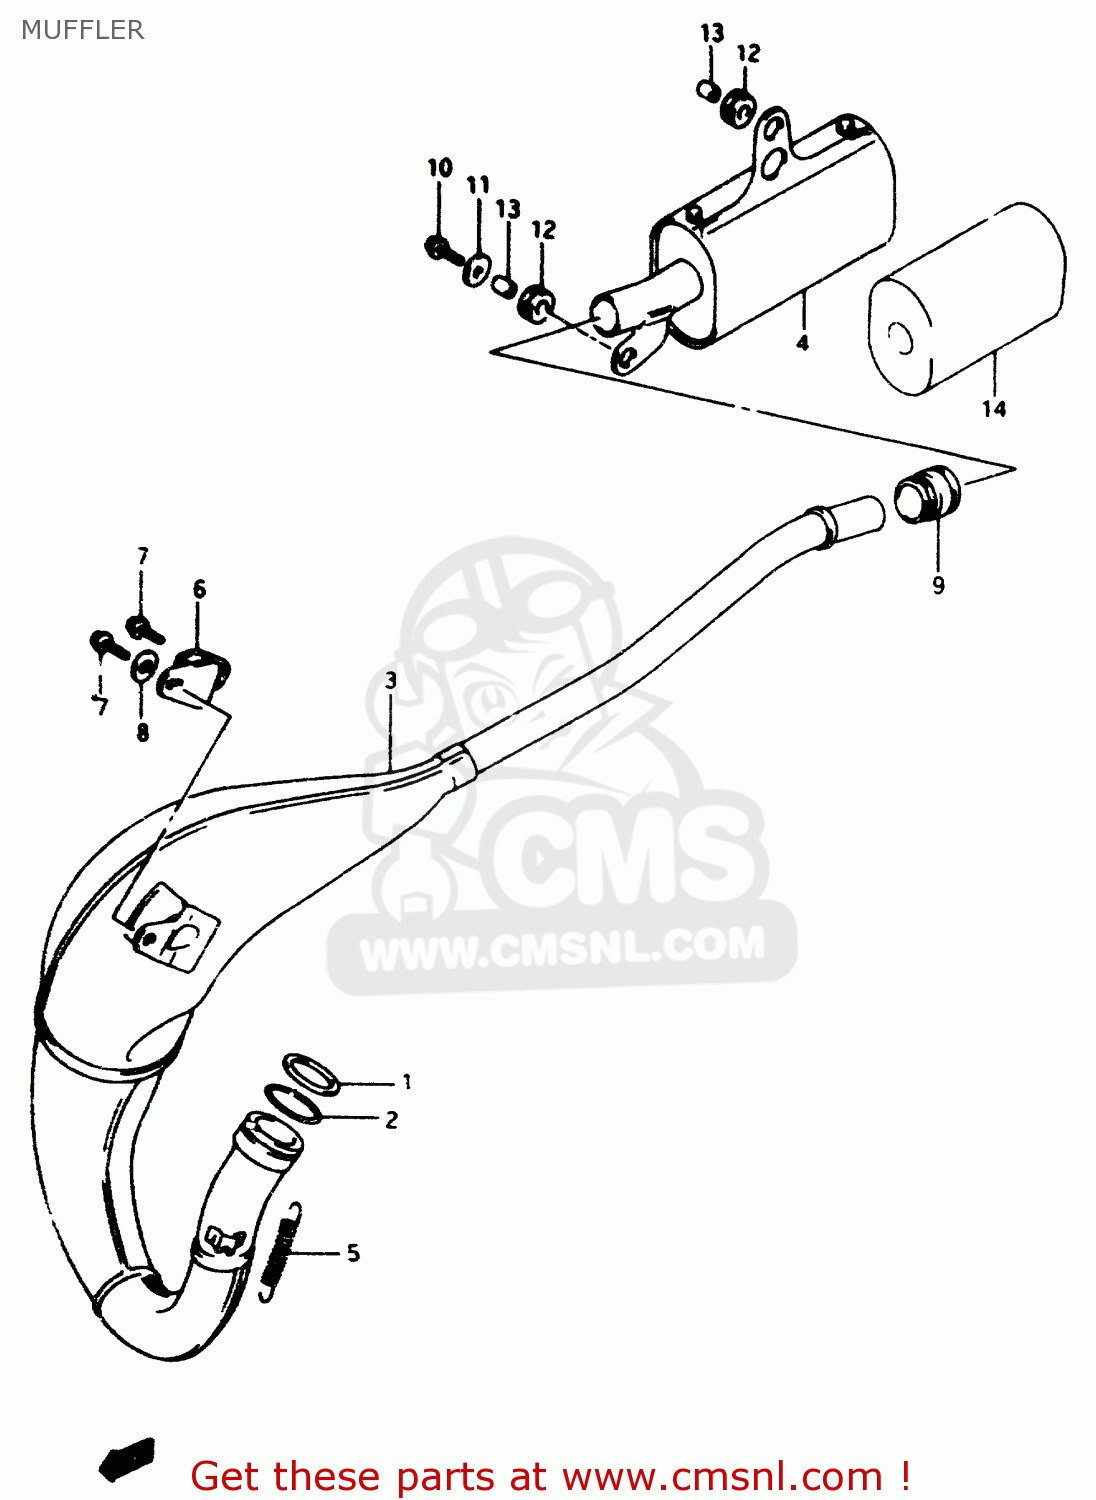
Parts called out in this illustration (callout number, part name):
1	WASHER,EXH FLANGE
2	O RING,EXH FLANGE
3	BODY,MUFFLER 1ST
4	BODY,MUFFLER,SECOND
5	SPRING
6	DAMPER,MUFFLER SUPPORT
7	BOLT
8	WASHER(6.5X16X1.2)
9	CONNECTOR,MUFFLER
10	SCREW
11	WASHER (6.5X20X1.2)
12	CUSHION
13	SPACER
14	SILENCER,MUFFL
